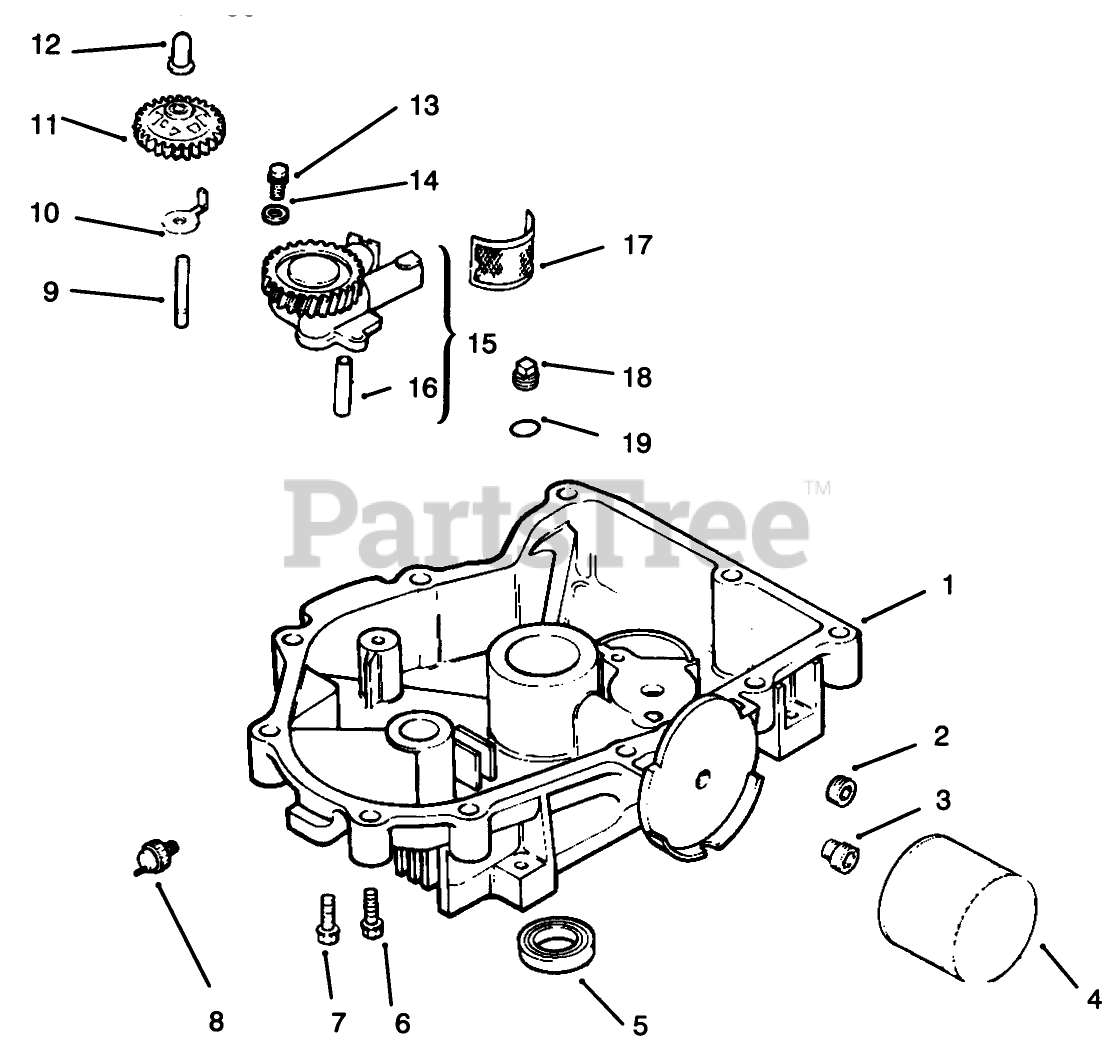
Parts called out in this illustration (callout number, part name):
1	Oil Pan (Only On: 72103)
2	Plug-HS 3/8 NPTF (Only On: 72103, 72083)
3	Nipple-Oil Filter
4	Filter-Oil
5	Seal-Oil
6	Screw M8x1.25x45 (Only On: 72103, 72083)
8	Switch-Oil Pressure
9	Shaft-Govenor Gear
10	Tab-Locking
11	Governor Gear ASM (Only On: 72103)
12	Pin-Governor
15	Oil Pump ASM INCL 16 (Only On: 72103)
16	Tube-Oil Pickup (Only On: 72103, 72083)
17	Screen-Oil Pickup (Only On: 72042, 72063, 72062, 72043)
